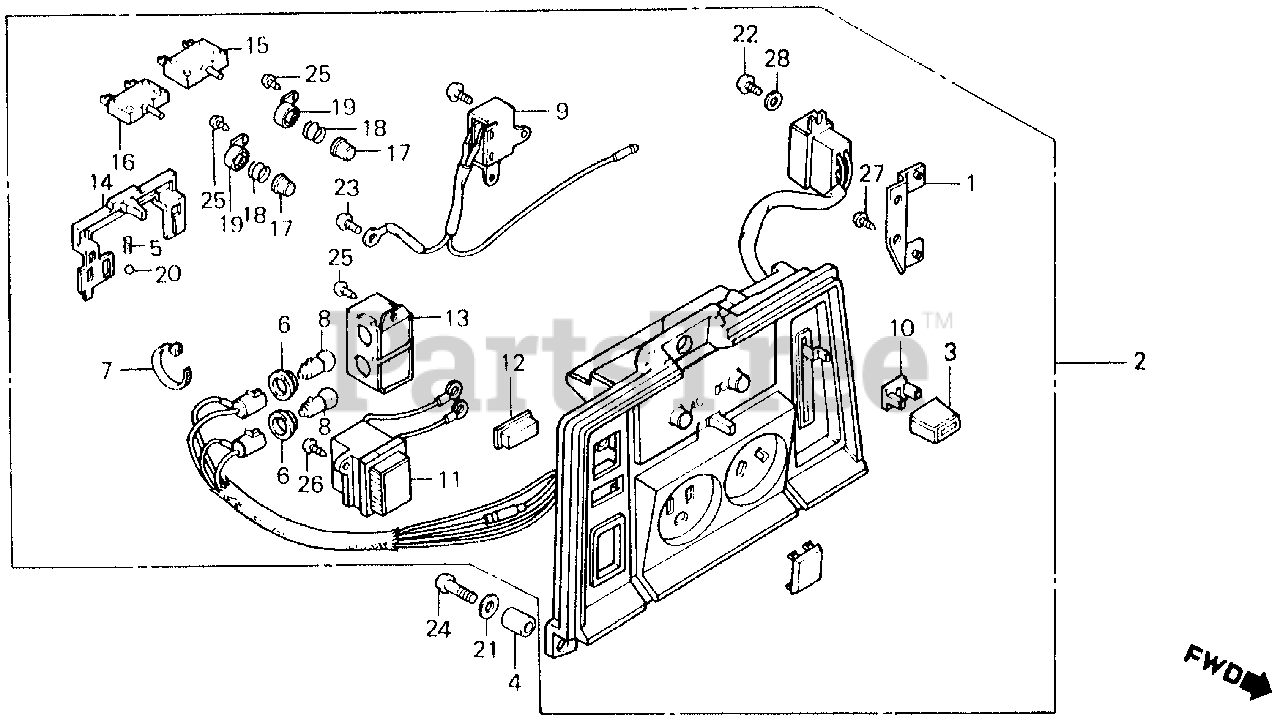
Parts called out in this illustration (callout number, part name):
1	STAY, CONNECTOR
2	PANEL ASSY. (NOT AVAILABLE)
3	KNOB, VALVE LEVER
4	COLLAR, PANEL
5	SPRING, CLICK
8	BULB, DASH (6V3W) (STANLEY)
9	SWITCH ASSY., STOP (NOT AVAILABLE)
10	BUSH, CONTROL KNOB
11	METER, FREQUENCY (NOT AVAILABLE)
12	LENS, PILOT LAMP (NOT AVAILABLE)
13	CASE, LAMP
14	SHUTTER
14	SHUTTER (NOT AVAILABLE)
15	PROTECTOR, CIRCUIT (12A) (NOT AVAILABLE)
16	PROTECTOR, CIRCUIT (3.5A) (NOT AVAILABLE)
16	PROTECTOR, CIRCUIT (5A)
17	CAP, BREAKER
18	SPRING, RETURN
19	HOLDER, BREAKER (NOT AVAILABLE)
20	BALL, CLICK
21	WASHER, STOPPER (5MM)
22	SCREW, PAN (3X8)
23	SCREW, PAN (3X10)
24	SCREW, PAN (5X12)
25	SCREW, TAPPING (3X6)
26	SCREW, TAPPING (3X12)
27	SCREW, TAPPING (4X20)
28	WASHER, PLAIN (3MM)
